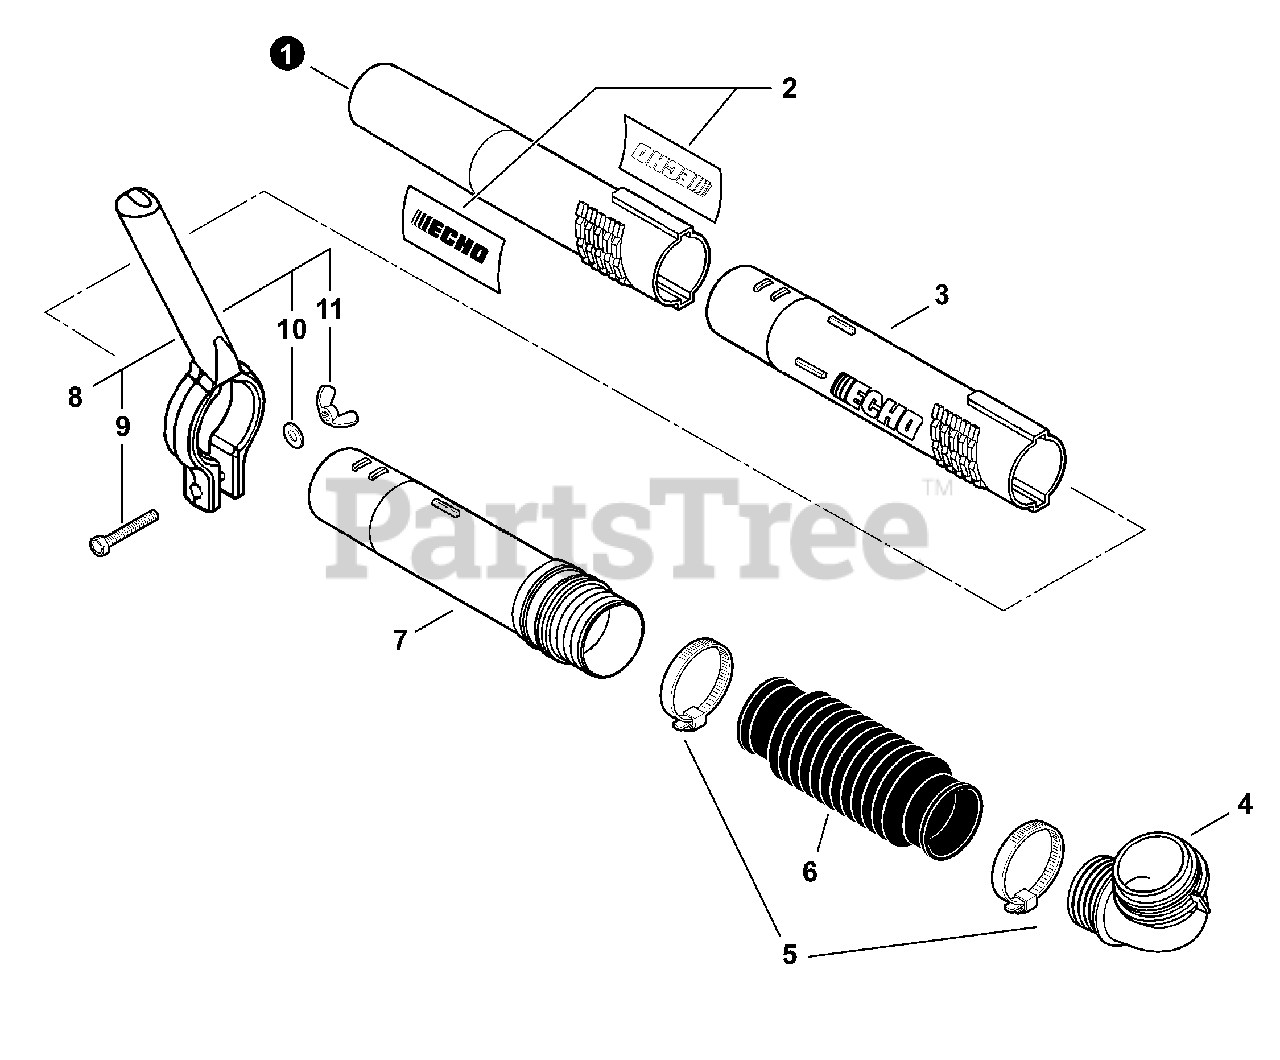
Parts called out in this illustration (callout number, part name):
1	TUBE, BLOWER - ROUND NOZZLE
2	LABEL, ECHO BLOWER TUBE
3	TUBE, BLOWER - STRAIGHT
4	TUBE, BLOWER - ELBOW
5	CLAMP 58.7 MM / 82.5 MM
6	TUBE, BLOWER - FLEXIBLE
7	TUBE, BLOWER - SWIVEL
8	HANDLE ASSY, PB LARGE
9	BOLT 6×45
10	WASHER 6.5×11.5×0.8
11	NUT, WING 6
